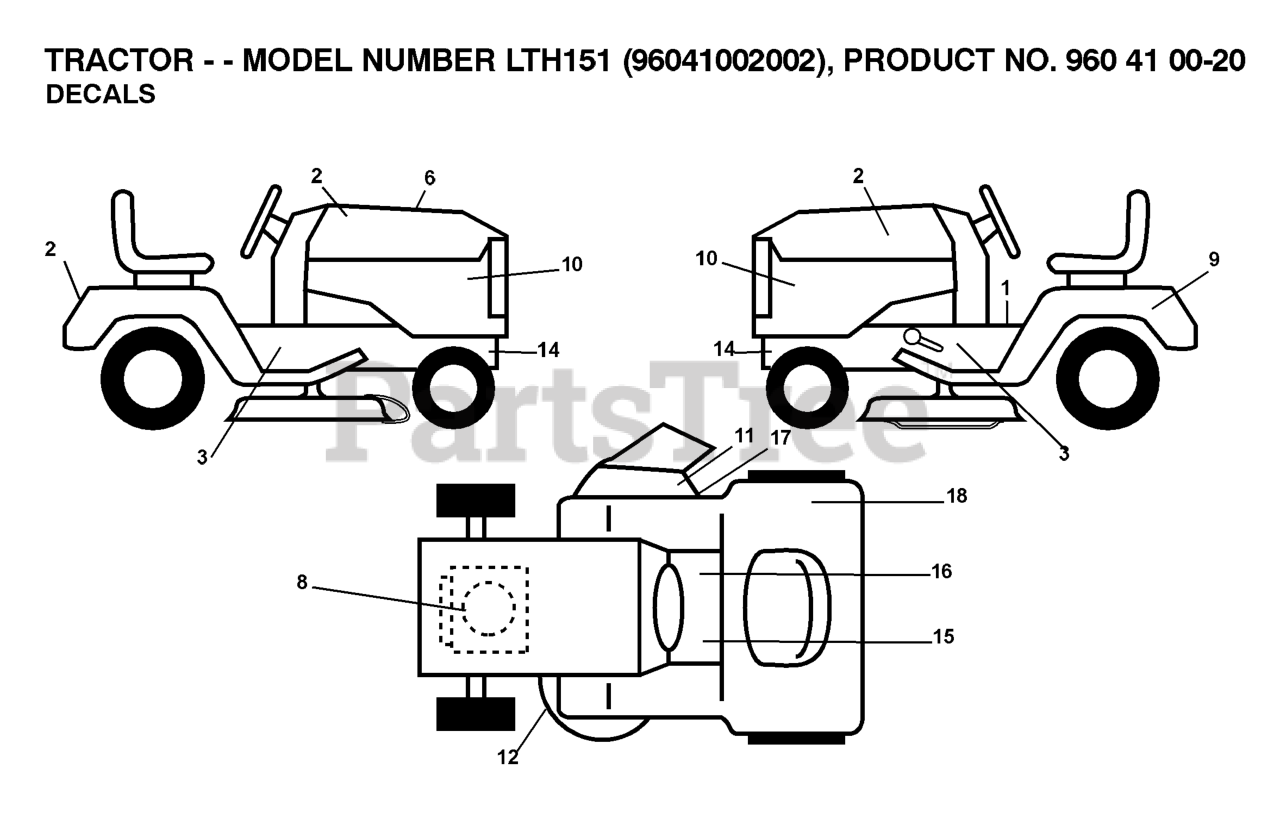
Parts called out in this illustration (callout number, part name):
1	LABEL
2	DECAL.HOOD.NAMELOGO.HUSQ
8	DECAL
9	DECAL BTRY SYMBOLS
10	DECAL SIDE PANEL
11	DECAL.INTERNATIONL.CUTFINGER
12	DECAL.V-BELT.SCHEMATIC.36/38/9
15	DECAL
16	DECAL PARK BRAKE
17	DECAL, DEFLECT WARNING
18	Decal, Fender 100 DB/CE
